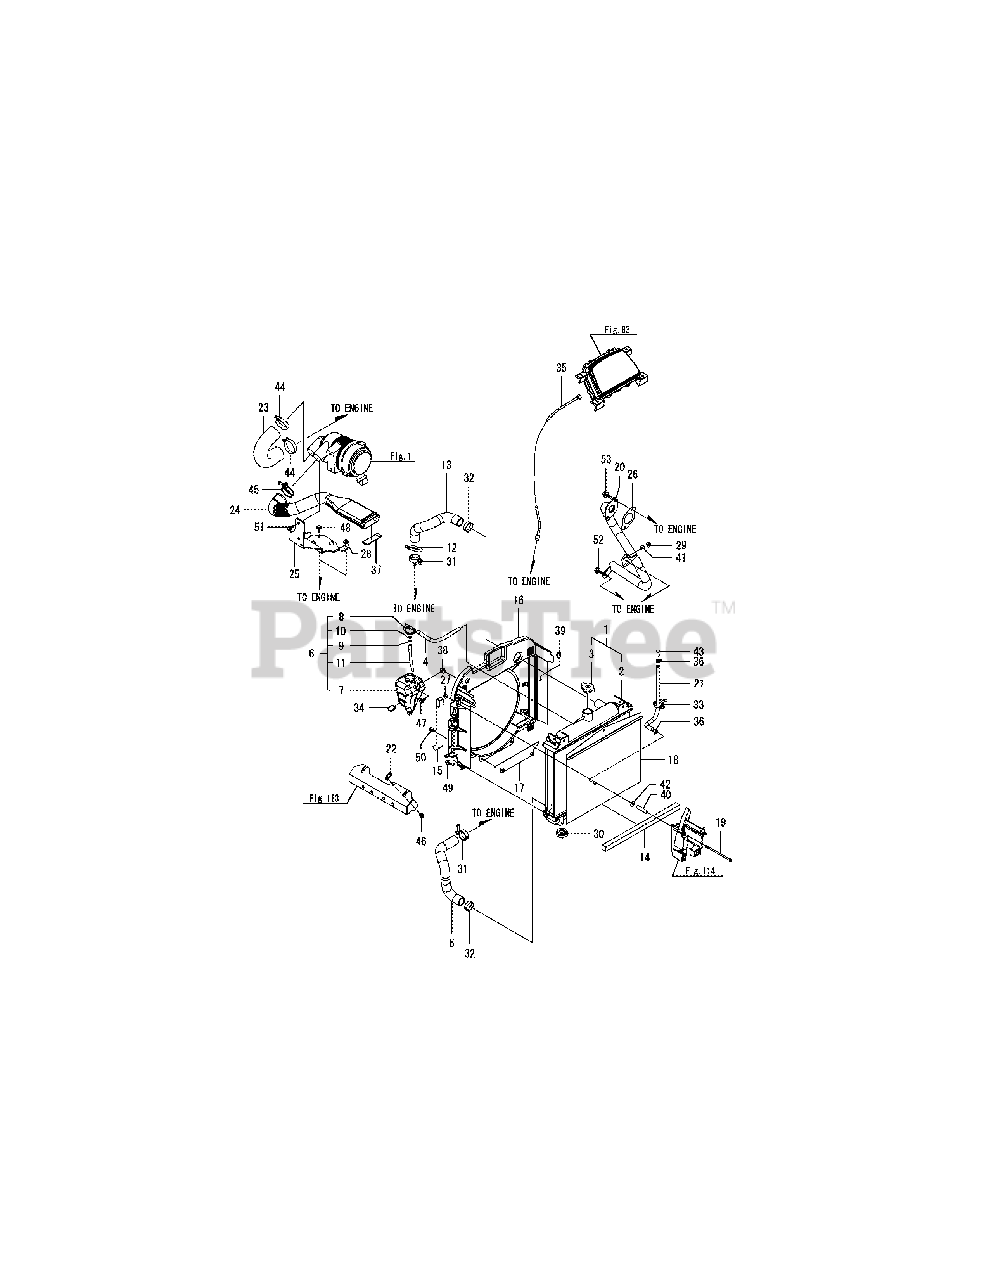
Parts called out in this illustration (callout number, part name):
3	Cap, Radiator D46
5	Pipe L 66,Cool.Water
6	Tank Assy,Coolant
13	Hose, Cooling Water
14	Seal, Radiator
15	Seal,Shroud Lower
16	Shroudm Assy, Fan
17	Plate Assy, Shroud
18	Screen, Radiator
22	Plate Assy, Mount
23	Hose, Air Intake
24	Air Intake Pipe
25	Bracket Assy, Air Cleaner
27	Nut W/Washer 6
28	Nut W/Washer 8
29	Nut W/Washer 8
35	Cable, Hour Meter
37	Seal E, Ladiator
40	Coller, 6.5X10X52
41	Washer 8, Polished
46	Bolt M 6X 12 Plated
47	Bolt M 6X 16 Plated
48	Bolt M 6X 16 Plated
49	Bolt M 6X 16 Plated
50	Bolt M 6X 16 Plated
51	Bolt M 8X 16 Plated
52	Bolt M 8X 16 Plated
53	Bolt M 8X 25 Plated
